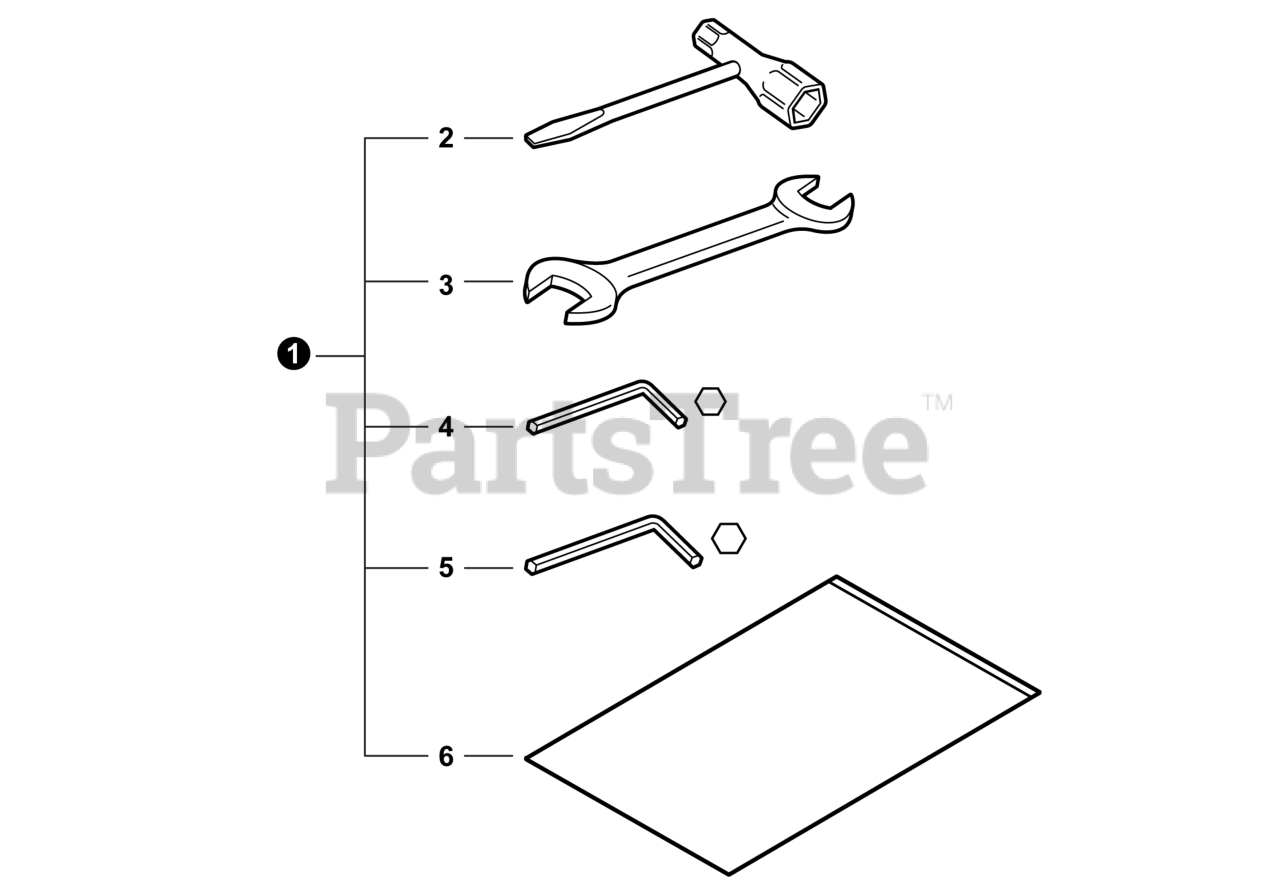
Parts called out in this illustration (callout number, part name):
1	TOOL KIT, SERVICE
2	T-WRENCH 16×13
3	SPANNER 8×10
4	WRENCH, ALLEN 3 MM
5	WRENCH, ALLEN 4 MM
6	BAG, TOOL
